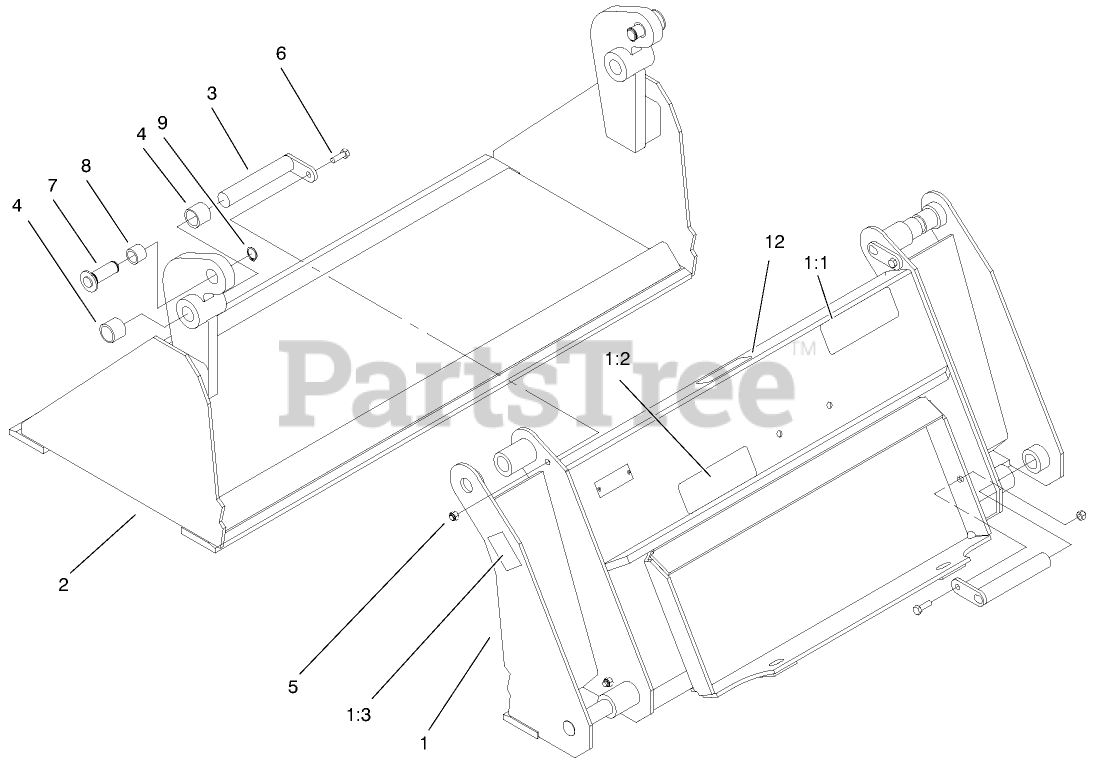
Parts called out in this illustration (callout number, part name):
1	Base ASM
1:1	DECAL-WARNING
1:2	DECAL-LOAD RATING
1:3	DECAL-WARNING
4	BUSHING
5	NUT-LOCK, NI
6	SCREW-HHF
8	BUSHING
9	Ring-Snap
12	DECAL-ATTACHMENT, DINGO
